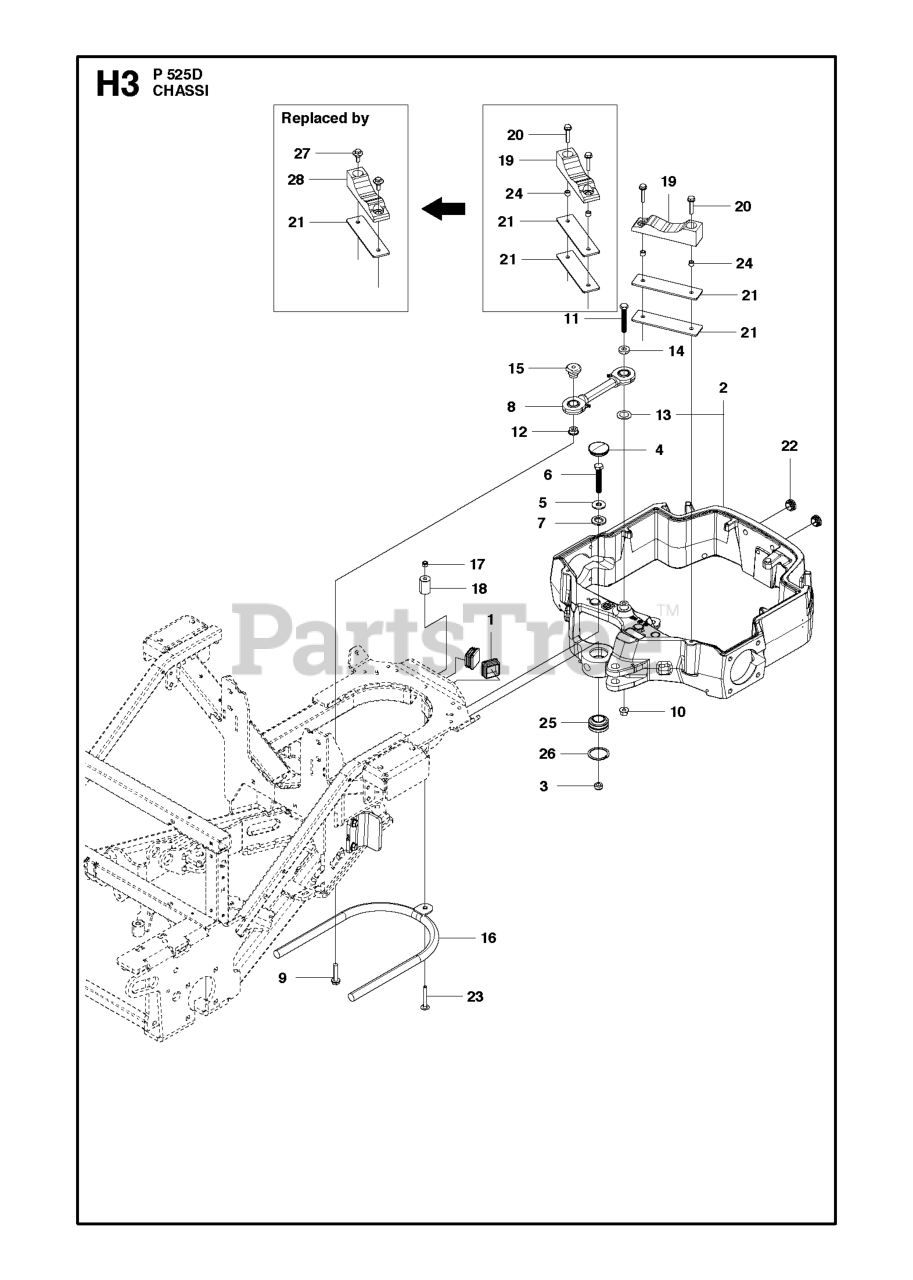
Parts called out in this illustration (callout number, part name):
17	LOCKNUT M8
20	SCREW EHHFM
27	COLLAR SCREW
